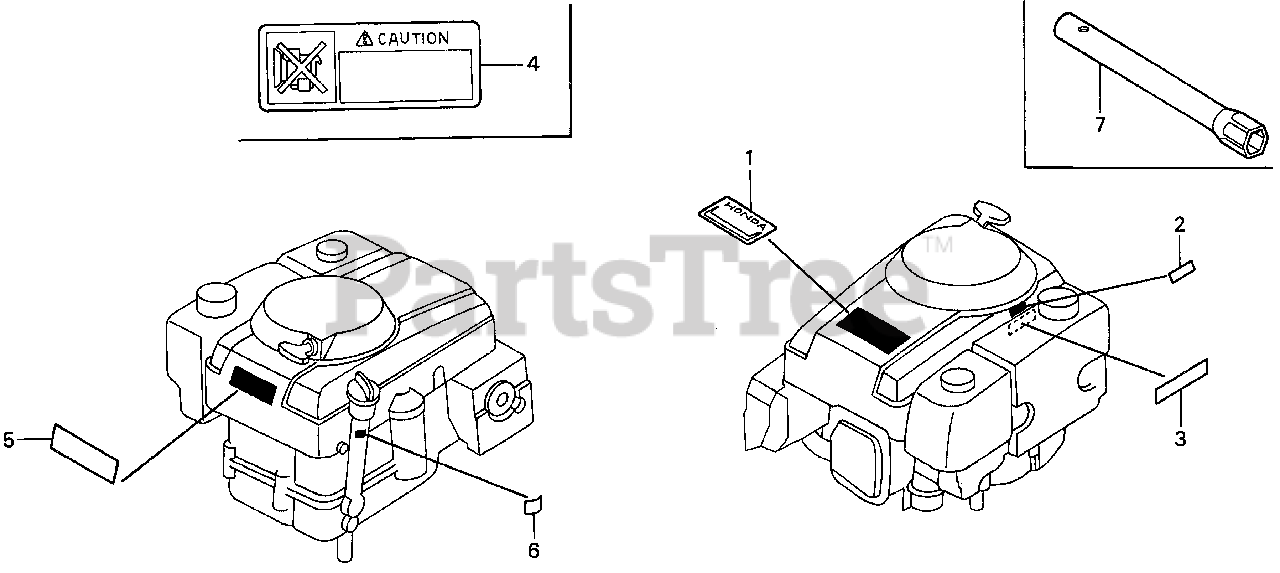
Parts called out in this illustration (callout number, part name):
1	MARK, TOP COVER EMBLEM (11.0)
5	LABEL, CAUTION
6	MARK, TYPE (DNE3)
